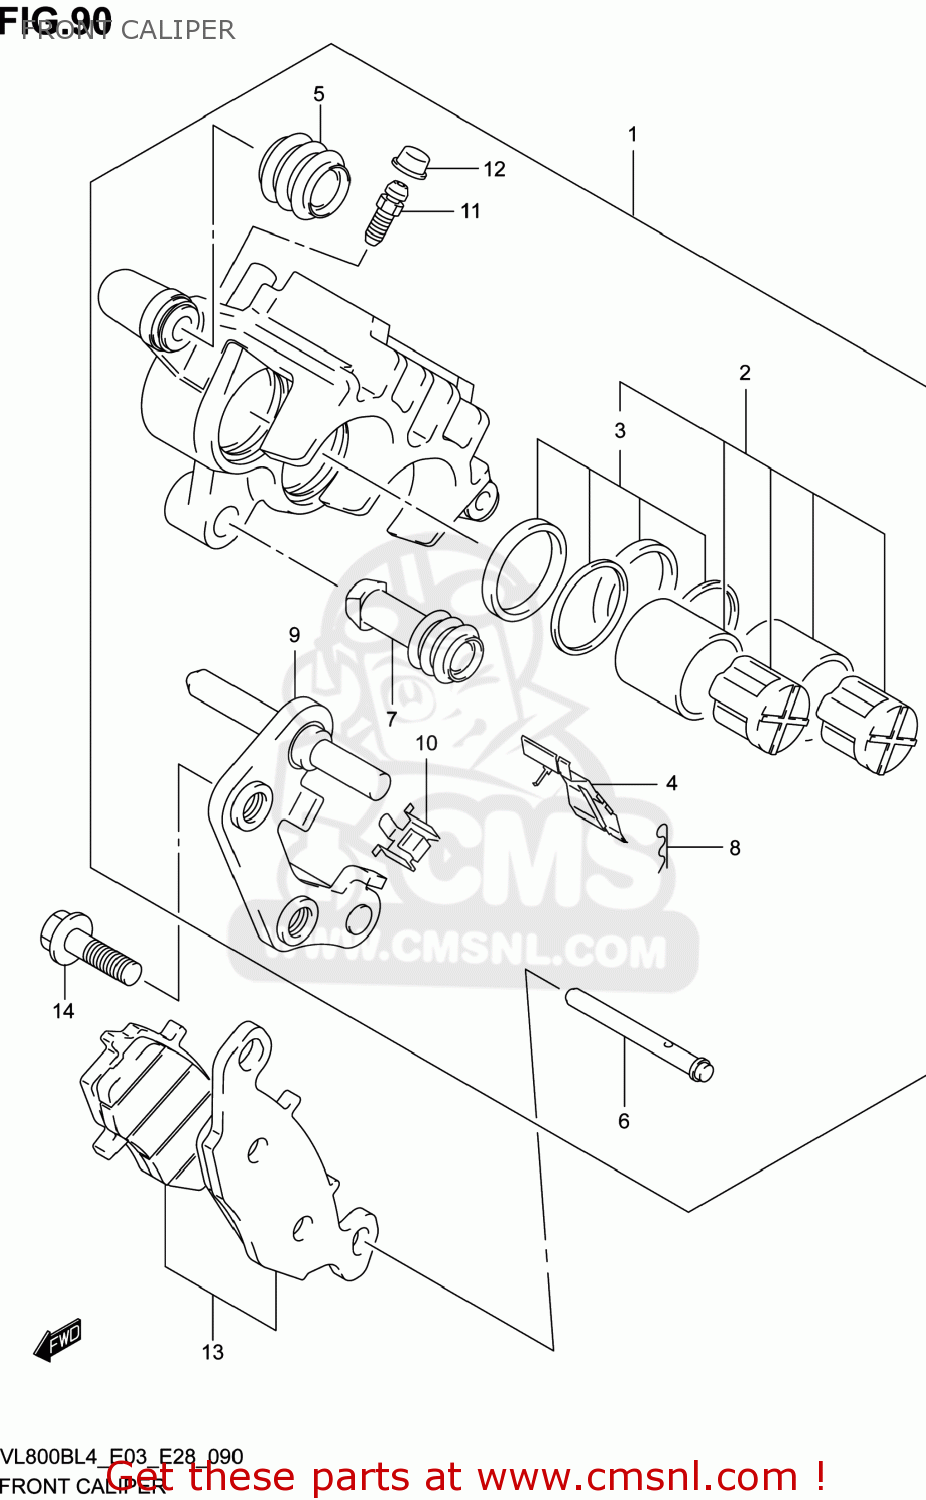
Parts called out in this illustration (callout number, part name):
1	CALIPER ASSY,FRONT,R
2	PISTON SET
3	SEAL SET,PISTON
4	SPRING,PAD,R
5	BOOT,AXLE
6	PIN,PAD
7	INSULATOR,AXLE
8	CLIP,PAD PIN
9	CARRIER,CALIPER,R
10	GUIDE,PAD
11	BLEEDER
12	CAP,BLEEDER PLUG
13	PAD SET (NAS)
14	BOLT(10X30)
